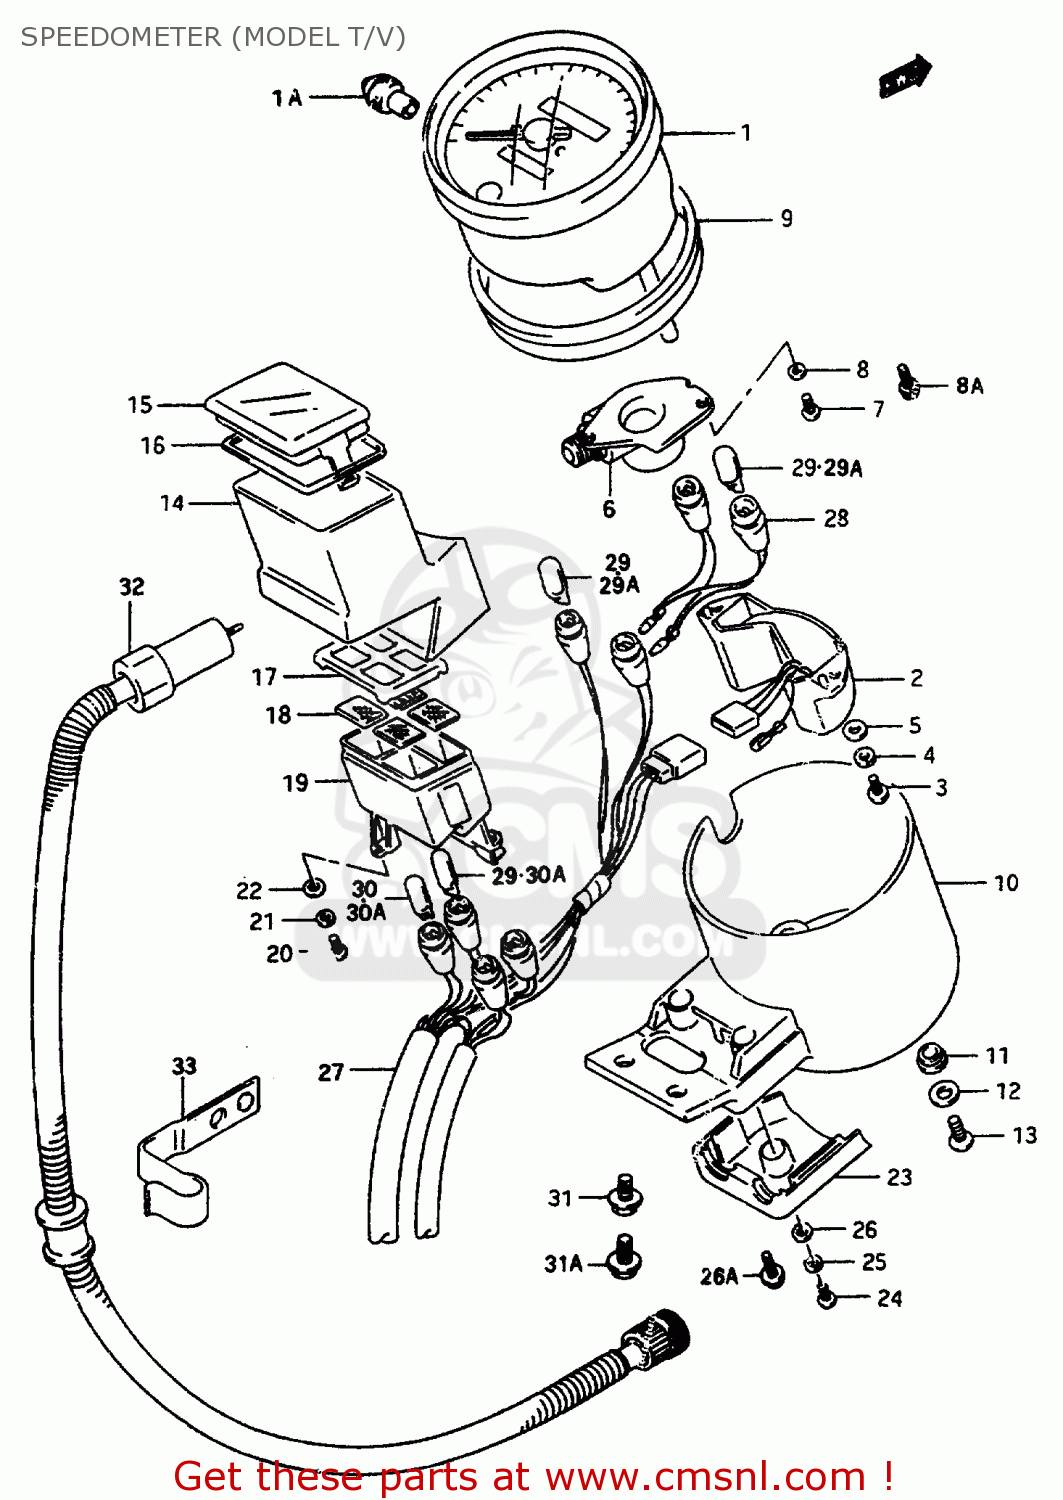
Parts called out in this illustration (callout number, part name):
1	SPEEDOMETER (MILE/KILO)
1A	KNOB,TRIP
2	UNIT,WATER TEMP
3	SCREW
4	WASHER,LOCK
5	WASHER
6	BOX,GEAR
7	SCREW
8	WASHER,LOCK
8A	SCREW
9	CUSHION
10	COVER,METER
11	CUSHION,METER
12	WASHER
13	SCREW
14	BOX,PILOT
15	LENS,PILOT BOX
16	CUSHION
17	PLATE,PILOT LENS
18	LENS SET
19	CASE,PILOT LAMP
20	SCREW
21	WASHER,LOCK
22	WASHER
23	COVER,PILOT BOX
24	SCREW
25	WASHER,LOCK
26	WASHER
26A	SCREW
27	SOCKET,METER NO.1
28	SOCKET
29	BULB(12V3W,T6.5)
29A	BULB(12V3W,T6.5)
30	BULB(12V1.7W,T6.5)
30A	BULB(12V1.7W,T6.5)
31	BOLT
31A	SCREW
32	CABLE ASSY,SPEEDOMETER
33	GUIDE,SPEEDOMETER CABLE
